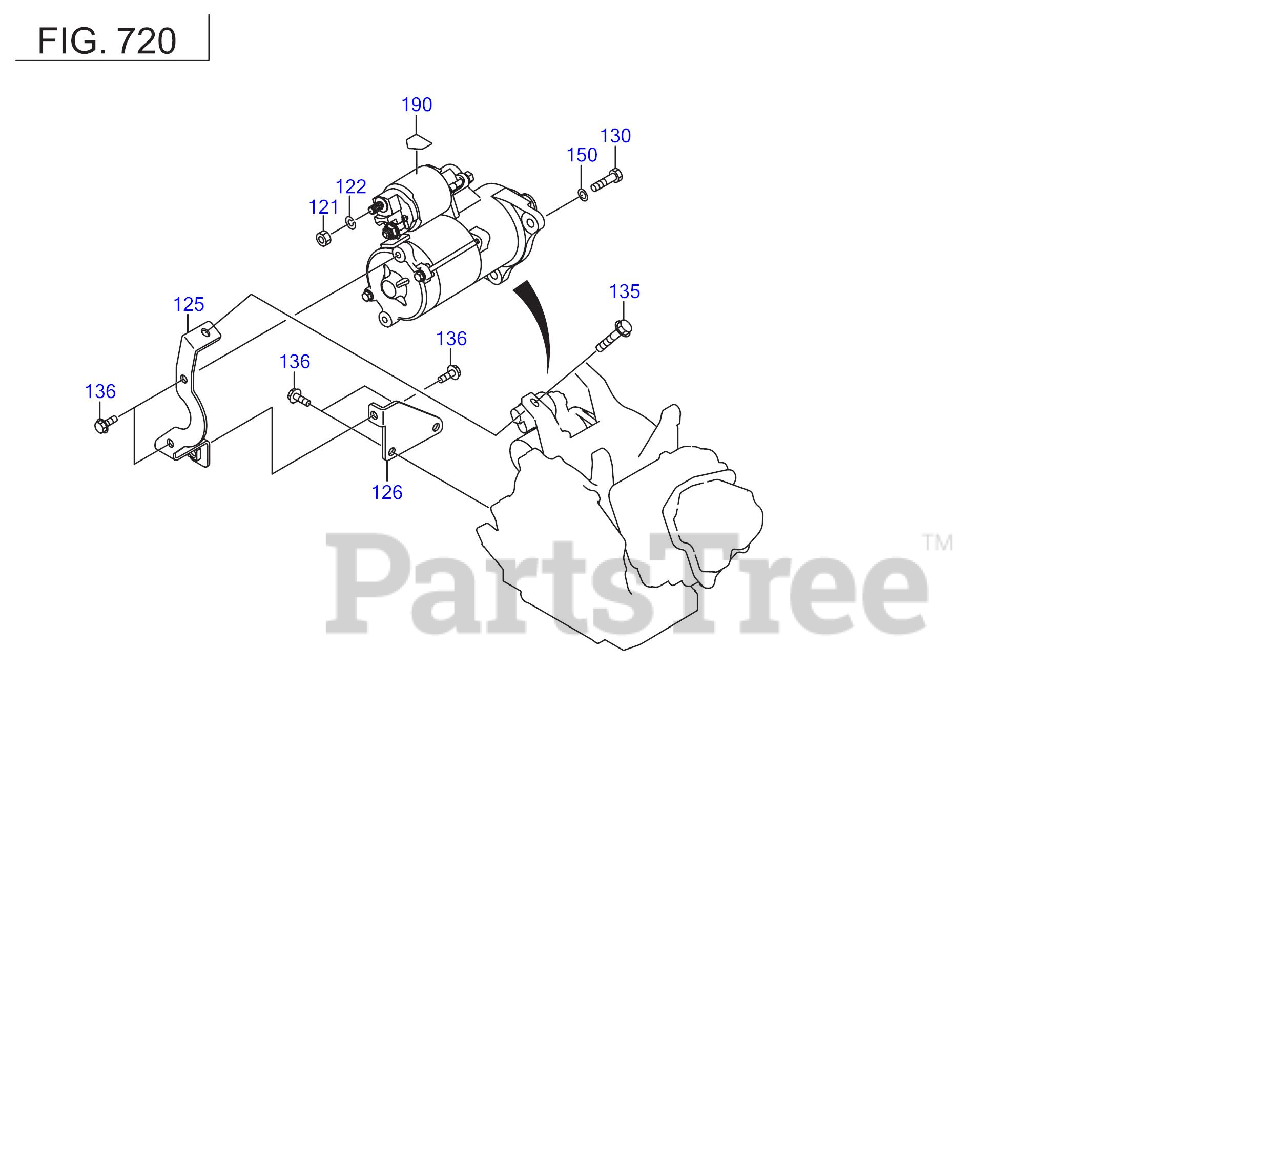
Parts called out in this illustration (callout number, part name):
125	BRACKET(SEL) 1 CP
126	BRACKET(SEL) 2
130	BOLT CP,STARTER
190	LABEL(BATTERY)
